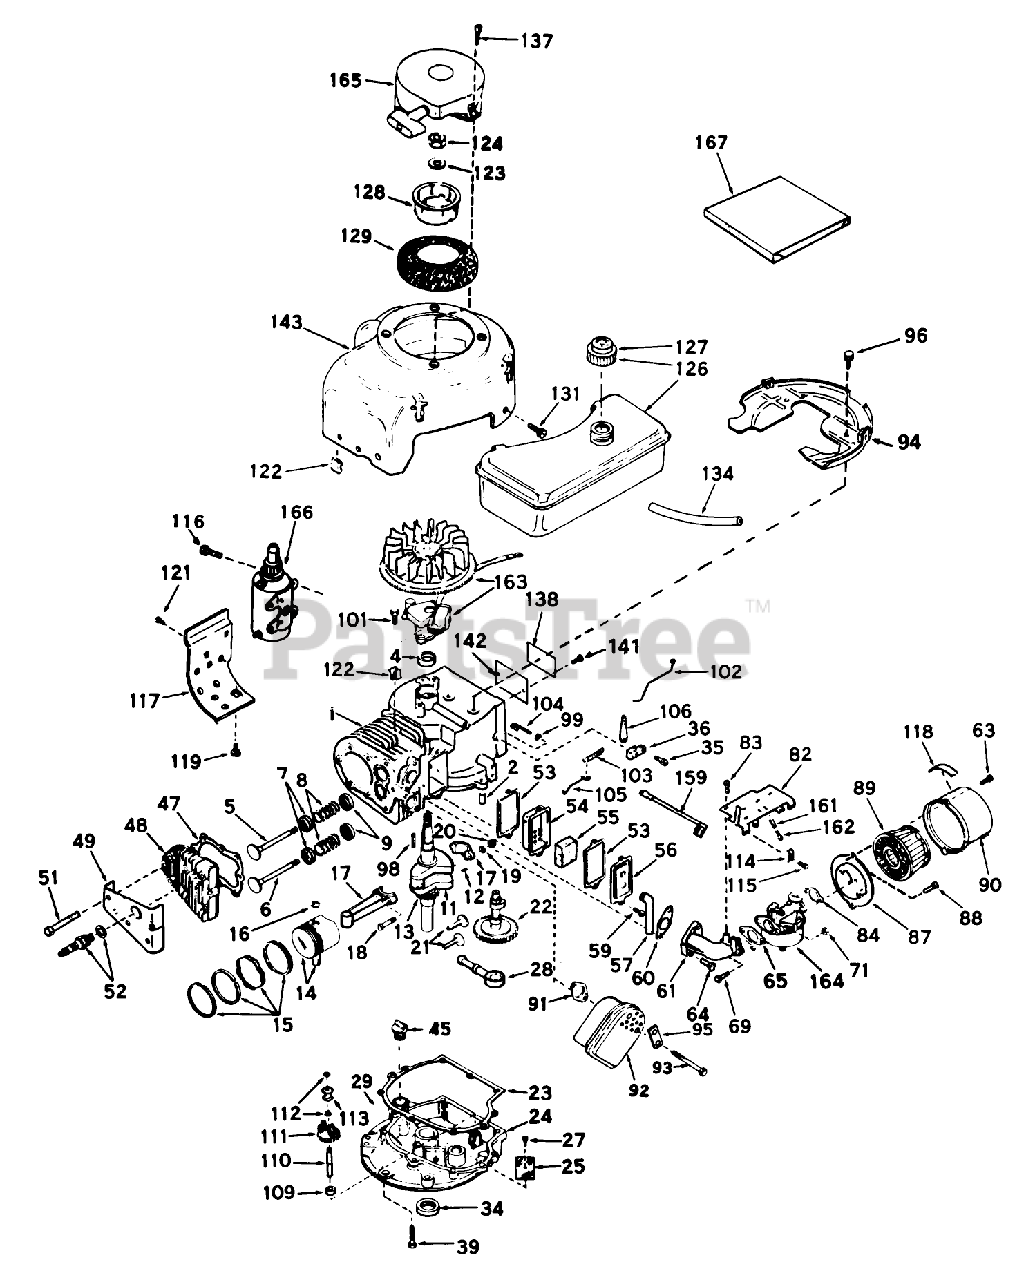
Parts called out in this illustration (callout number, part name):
1	Cylinder Assy. (Incl. Nos. 2 4)
2	Pin-Dowel
4	Seal, Oil
5	Valve, Intake (Std.)(Incl. No. 9)
5	Valve, Intake (1 /32" oversize)(Incl. No. 9)
6	Valve, Exhaust (Standard)(Incl. No. 9)
6	Valve, Exhaust (1/32" oversize)(Incl. No. 9)
7	Cap-Spring, Valve
8	Spring-Valve
9	Keeper-Spring, Valve
11	Crankshaft Assy. (Incl. Nos. 12 13)
12	Pin, Groove
13	Gear-Crankshaft
14	Piston Pin Assy. (Standard)(Incl. 2 of No. 16)
14	Piston Pin Assy. (.010 oversize)(Incl. 2 of No. 16)
14	Piston Pin Assy. (.020 oversize)(Incl. 2 of No. 16)
15	Ring Set, Piston (Std.)
15	Ring Set, Piston (.010 Oversize)
15	Ring Set, Piston (.020 oversize)
17	Rod Assy., Connecting (Incl. Nos. 18, 19 20)
18	Bolt, Connecting Rod
19	Washer
21	Lifter Valve
22	Camshaft (Compression Release)
23	Gasket-Cover, Cylinder
24	Flange Assy., Mounting (Incl. Nos. 25, 27, 29, 34, 45 110)
25	Screen-Oil Filter
27	Screw
28	Pump, Oil
29	Plug-Drain, Oil (SQH 1/4-18)
34	Seal-Oil
35	Screw
36	Clamp-Lever, Governor
39	Screw (1/4-20 x 1-1/4)
45	Plug-Fill, Oil
47	Gasket-Head, Cylinder
48	CYLINDER HEAD
49	Cover-Head, Cylinder
51	Screw Hex Hd. Cap
52	SPARK PLUG
53	Gasket-Breather
54	Body-Breather
55	Element-Breather
56	Cover-Valve
57	Tube-Breather
59	Screw
60	Gasket-Intake
61	Pipe, Intake
63	Screw
64	Screw (T-30, 5/16-18x1-3/32)
65	Gasket
71	Nut and Lock Washer (1/4-28)
82	Control Assy., Speed (Incl. Nos. 161 162)
83	Screw (10-24 x 9/16)
84	Gasket
87	Bracket
88	Screw (10-32 x 1/2)
89	Element
90	Body
91	Gasket Exhaust
92	Muffler
93	Screw Hex Hd.
94	Baffle Blower Housing
95	62513 SNWTHWR W/284
96	Screw (1/4-20x19/32)
98	Key, Flywheel
99	Washer-Flat
101	Screw
102	Link Governor
103	Spring Governor
104	Rod, Governor (Incl. Nos. 146)
105	Link Governor Spring
106	Lever-Governor
109	Spacer
110	Shaft, Governor
111	Governor Gear ASM
112	Ring-Retaining
113	Spool-Governor
114	Conduit
115	Screw (10-32 x 3/8)
116	Screw
117	Emnsion, Blower Housing
118	Decal
119	Screw
121	Screw
122	51004 GIL ROTARY TI
123	Washer
126	1580F GIL 5HP ROTAR
127	Cap, Fuel
128	Cup-Starter
129	Screen, Air
131	Screw, Hex Hd.
134	Line-Fuel (8.62)
137	Screw
138	480B GIL SNWTHWR O/
141	Stud
142	IDENTIFICATION PLATE
143	Housing Blower
159	Wire, Ground
161	Spring-Compression
162	Screw
163	Magneto
164	Carburetor
165	Starter, Rewind
166	Motor, Starter
167	Gasket Set (Incl. items marked*)
